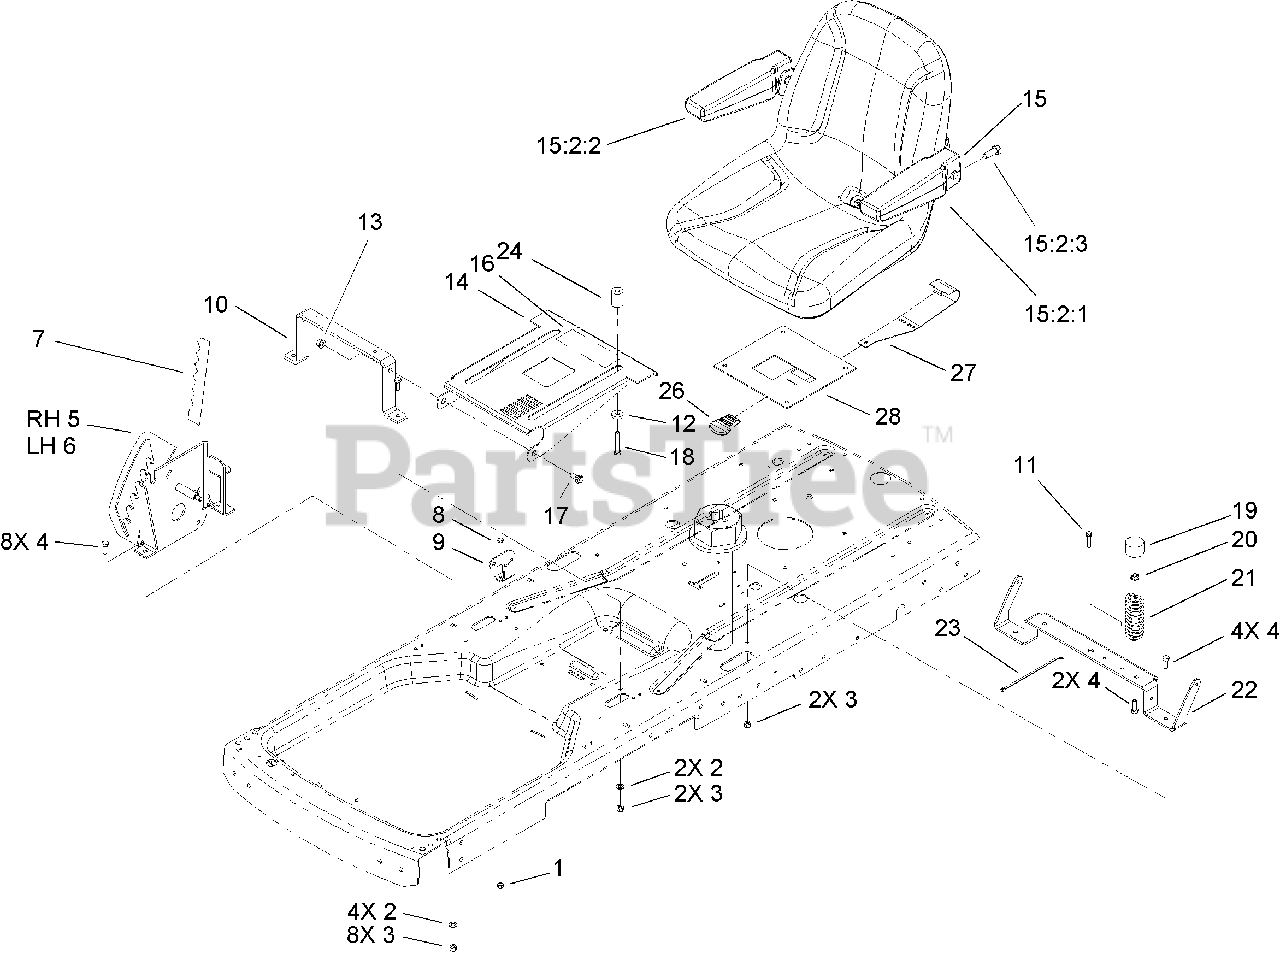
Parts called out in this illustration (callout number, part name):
1	NUT-LOCK, NI
2	WASHER-FLAT
3	NUT-LOCK, NI
4	SCREW-HH
5	RH PLATE ASM
6	LH PLATE ASM
7	DECAL-HOC
8	SCREW-HH
9	BRACKET-BELLCRANK
10	BRACE-SEAT, FRONT
11	SCREW-HWHTF
14	BRACKET-SEAT
15	SEAT ASM
15:2:1	LH ARMREST ASM
15:2:2	RH ARMREST ASM
15:2:3	SCREW-HSBH
16	DECAL-SERVICES
17	BOLT-SHOULDER
18	SCREW-HH
19	CAP-PROTECTOR
21	SPRING-COMPRESSION
22	BRACE-SEAT, REAR
23	STRAP-TIE
26	KNOB-LEVER, HOC
27	LATCH-SEAT
28	MOUNT-LATCH, SEAT
